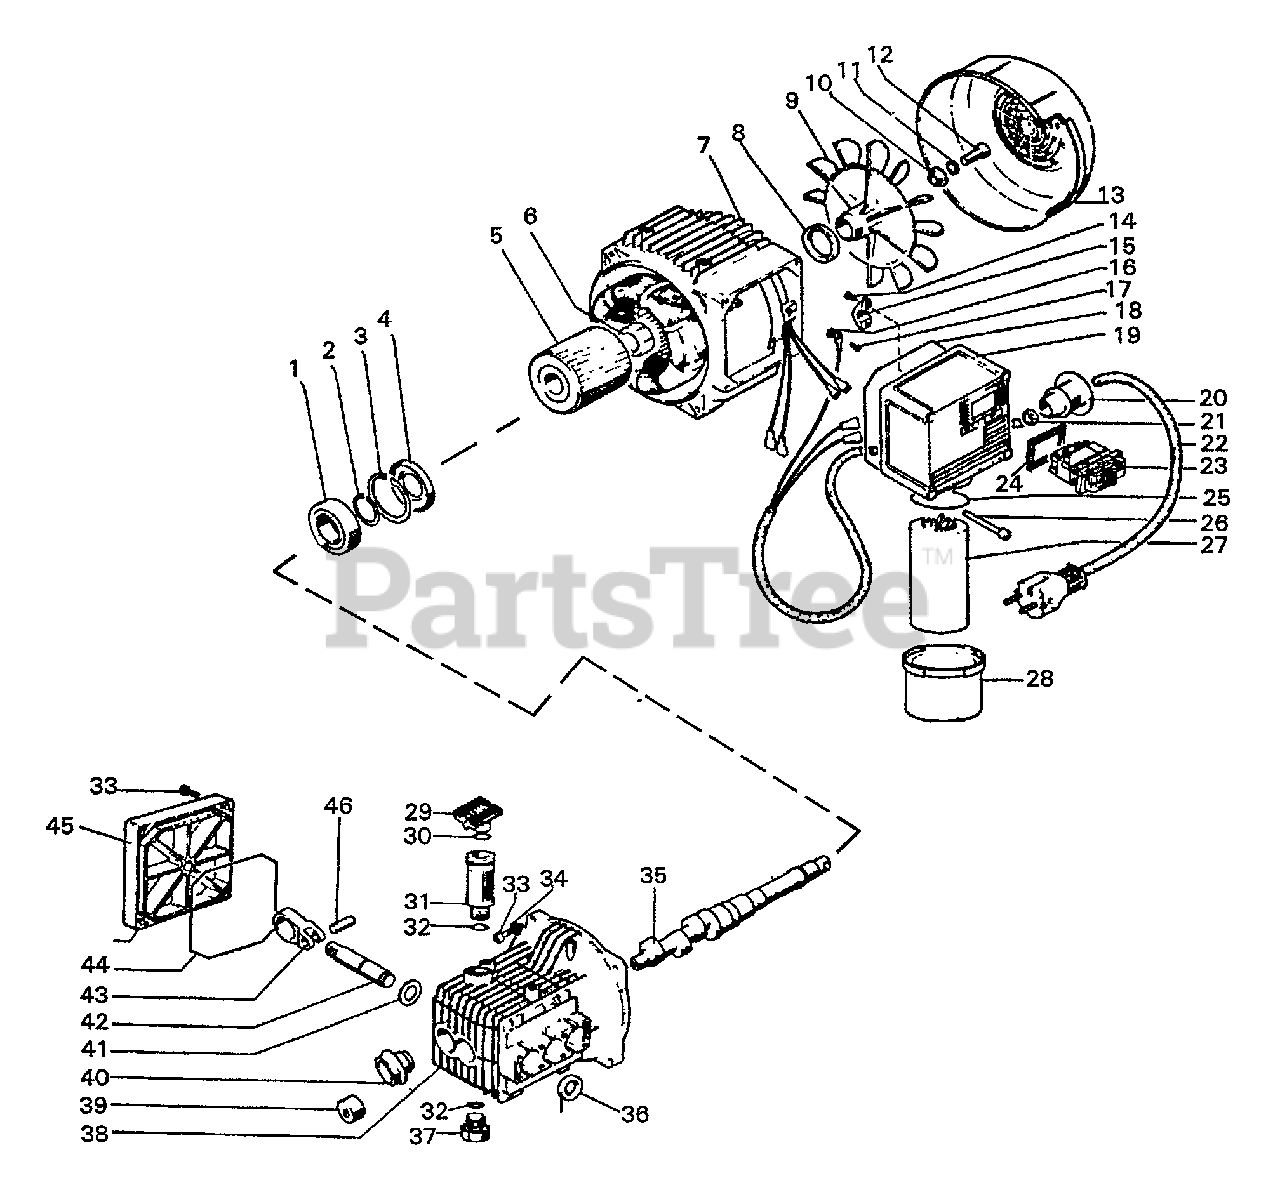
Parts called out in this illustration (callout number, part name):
1	BEARING, BALL
2	RING, RETAINING
3	RING, RETAINING
4	SEAL, OIL
5	ROTOR
6	NUT - 22
7	STATOR
8	SEAL
9	FAN
10	SPACER, FAN
11	WASHER
12	SCREW - 8X20
13	COVER, FAN
14	SCREW
15	CLAMP
16	WASHER
17	SCREW - 5X12
18	O-RING
19	COVER, SWITCH
20	HOLDER, CABLE
21	GROMMET, CORD GRIP
22	CABLE ASSY
23	SWITCH, IGNITION
24	GASKET, SWITCH
25	O-RING, 1.925 X .103
26	SCREW - 5X65
27	CONDENSER
28	COVER, CAPACITOR
29	COVER, OIL FILTER
30	O-RING
31	SPACER, DIPSTICK
32	O-RING
33	SCREW - 6X25
34	LOCKWASHER - 6
35	CRANKSHAFT ASSY
36	OIL SEAL KIT
37	PLUG
38	CRANKCASE
39	BEARING, NEEDLE
40	INDICATOR - OIL LEVEL
41	WASHER
42	PISTON - STAINLESS
43	ROD, CONNECTING
44	GASKET, COVER
45	COVER, CRANKCASE
46	PIN, CONNECTING ROD
